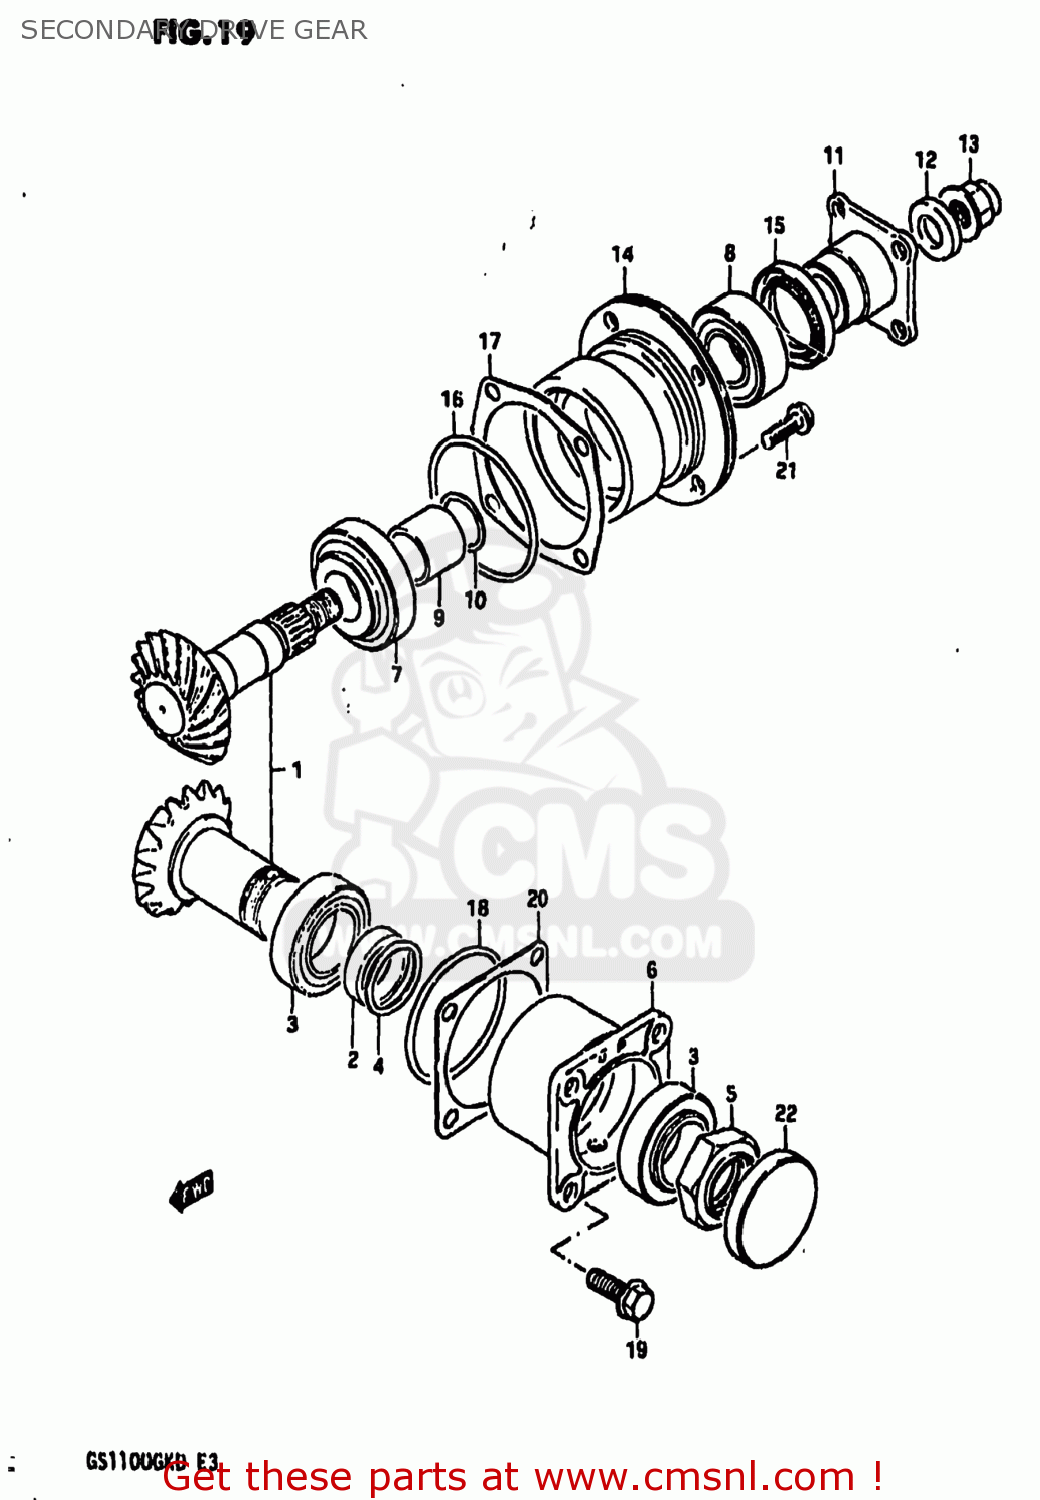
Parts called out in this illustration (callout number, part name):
1	SECONDARY GEAR SET
2	SPACER (32.4X38X12.5)
3	BEARING(32X58X17)
4	SHIM(32X38X2)
5	NUT
6	HOUSING,SECONDARY DRIVE
7	TAPER,ROLLER BEARING
8	BEARING
9	SPACER (25.2X30X40)
10	SHIM (25X30X2
11	FLANGE,UNIVERSAL JOINT
12	WASHER(14X29X4)
13	NUT
14	HOUSING,SECONDARY DRIVE
15	SEAL,OIL(35X52X9)
16	O RING(D:3.1,ID:69.4)
17	SHIM,DRIVEN GEAR HOUSING
18	O RING(D:2.4,ID:62.6)
19	BOLT
20	SHIM,SECONDARY DRIVE
21	BOLT
22	PLUG
